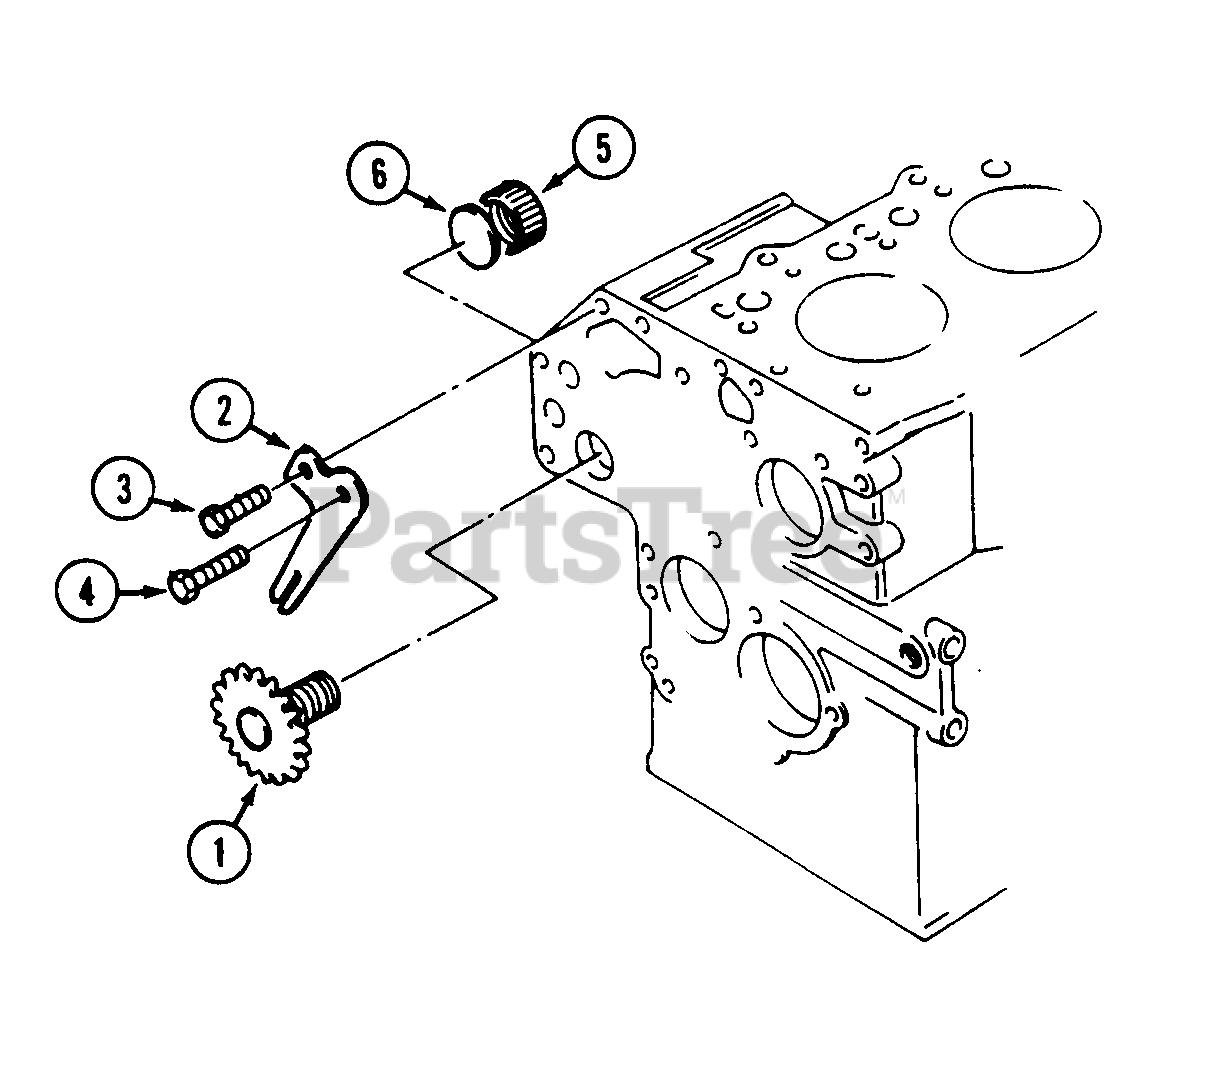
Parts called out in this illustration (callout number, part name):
1	SHAFT
2	PLATE
3	SCREW
4	SCREW
5	CAP
6	SEAL
